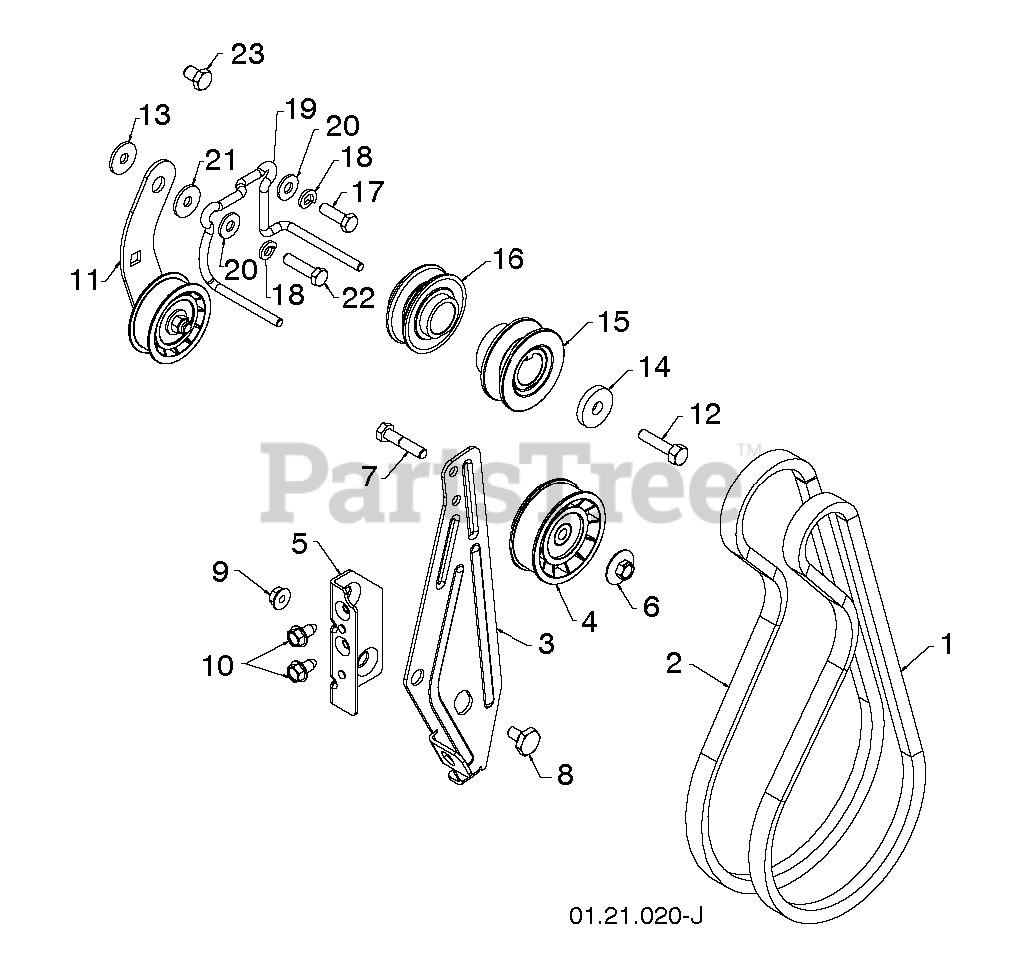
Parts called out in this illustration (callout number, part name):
1	V-BELT.IMPELLER
2	TRACTION BELT
3	ARM.IDLER BRAKE.CLEAR.ZINC
4	PULLEY.W/SPACER.2.75
5	BRACKET.IDLER.PIVOT.ZINC
6	NUT.FLANGE.HEX.5/16X18.BLACK
7	HEX BOLT
8	BOLT.SHOULDER.1/2X12
9	NUT.LOCK.5/16-18
10	BOLT.5/16HEX.WHS.HD
11	ARM.ASM.TRACTION.IDLER.
12	SCREW, HEX HD 3/8-24 X 1-3/8
13	STEEL WASHER
14	WASHER.400X1.25X5.
15	PULLEY ASM.IMP.2.60
16	PULLEY.ASM.ENG.TRACTION
18	WASHER.LOCK.HVY.HLCL.SPR.5/16
19	GUIDE.BELT.CHAIN.LS.SNOW
20	WASHER.20X8.5
21	RP BUSHING, IDLER PIVOT
22	CAPSCREW.HEXHD.5/16X1.25.
23	SCREW.3/8-16 X .750 (2 2)
